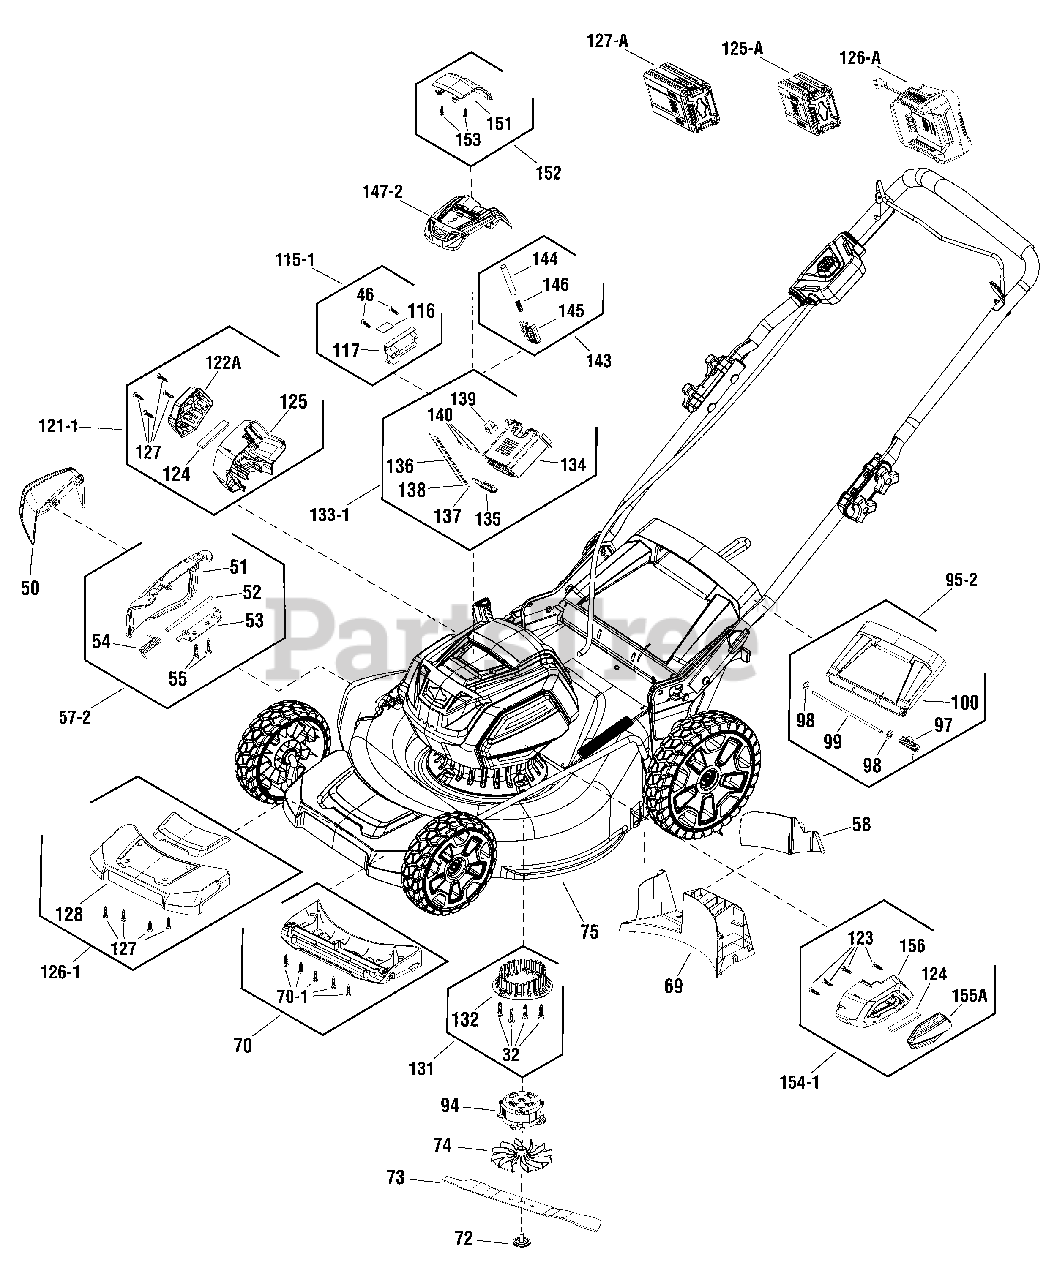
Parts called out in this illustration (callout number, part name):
32	SCREW
46	SCREW
50	KIT, DEFLECTOR, EU
51	COVER
52	SHAFT
53	STENTS
54	SPRING
55	BOLT
57-2	KIT, COVER, EU (Incl. Ref. 51 through 55)
58	KIT, PLUG
69	KIT, BACK BULKHEAD
70	KIT, FRONT BULKHEAD
70-1	SCREW
72	KIT, BOLT
73	KIT, BLADE
74	KIT, FAN
75	KIT, DECK
94	KIT, MOTOR
95-2	KIT, REAR COVER ASSEMBLY, EU (Incl. Ref 97 through 100)
97	SPRING
98	COTTER PIN
99	SHAFT
100	COVER, REAR
115-1	KIT, PCB EU (Incl. Ref 116,117 & 46)
116	SENSOR
117	21" PCB
121-1	KIT, RIGHT COVER (Incl. Ref 122A through 125)
122A	SIDE COVER, RIGHT
123	SCREW
124	DUST SCREEN
125	MAIN HOUSE, RIGHT
125-C	BATTERY, 2AH, EU (OPTION)
126-1	KIT, FRONT PANEL (Incl. Ref. 127 through 129)
126-C	CHARGER, RAPID, EU (OPTION)
127	SCREW
127-C	BATTERY, 4AH, EU (OPTION)
128	MAIN BODY, BUMPER
129	COVER, BUMPER
131	KIT, BASE (Incl. Ref. 32 & 132)
132	THE BASE
133-1	KIT, BATTERY COMPARTMENT ASSEMBLY, EU (Incl. Ref. 134 through 140)
134	CAVITY, BATTERY PACK
135	INSERT
136	WIRE, RED
137	WIRE, YELLOW
138	WIRE, BLACK
139	THE SHELL
140	TERMINAL
143	KIT, BUTTON (Incl. Ref. 144 through 146)
144	SHAFT
145	BUTTON
146	SPRING
147-2	KIT, TOP COVER, EU
151	BATTERY DOOR
152	KIT, BATTERY COVER (Incl. Ref. 151 & 153)
153	SCREW
154-1	KIT, LEFT COVER (Incl. Ref. 155A, 156, 123, 124)
155A	COVER, LEFT SIDE
156	MAIN HOUSING, LEFT
